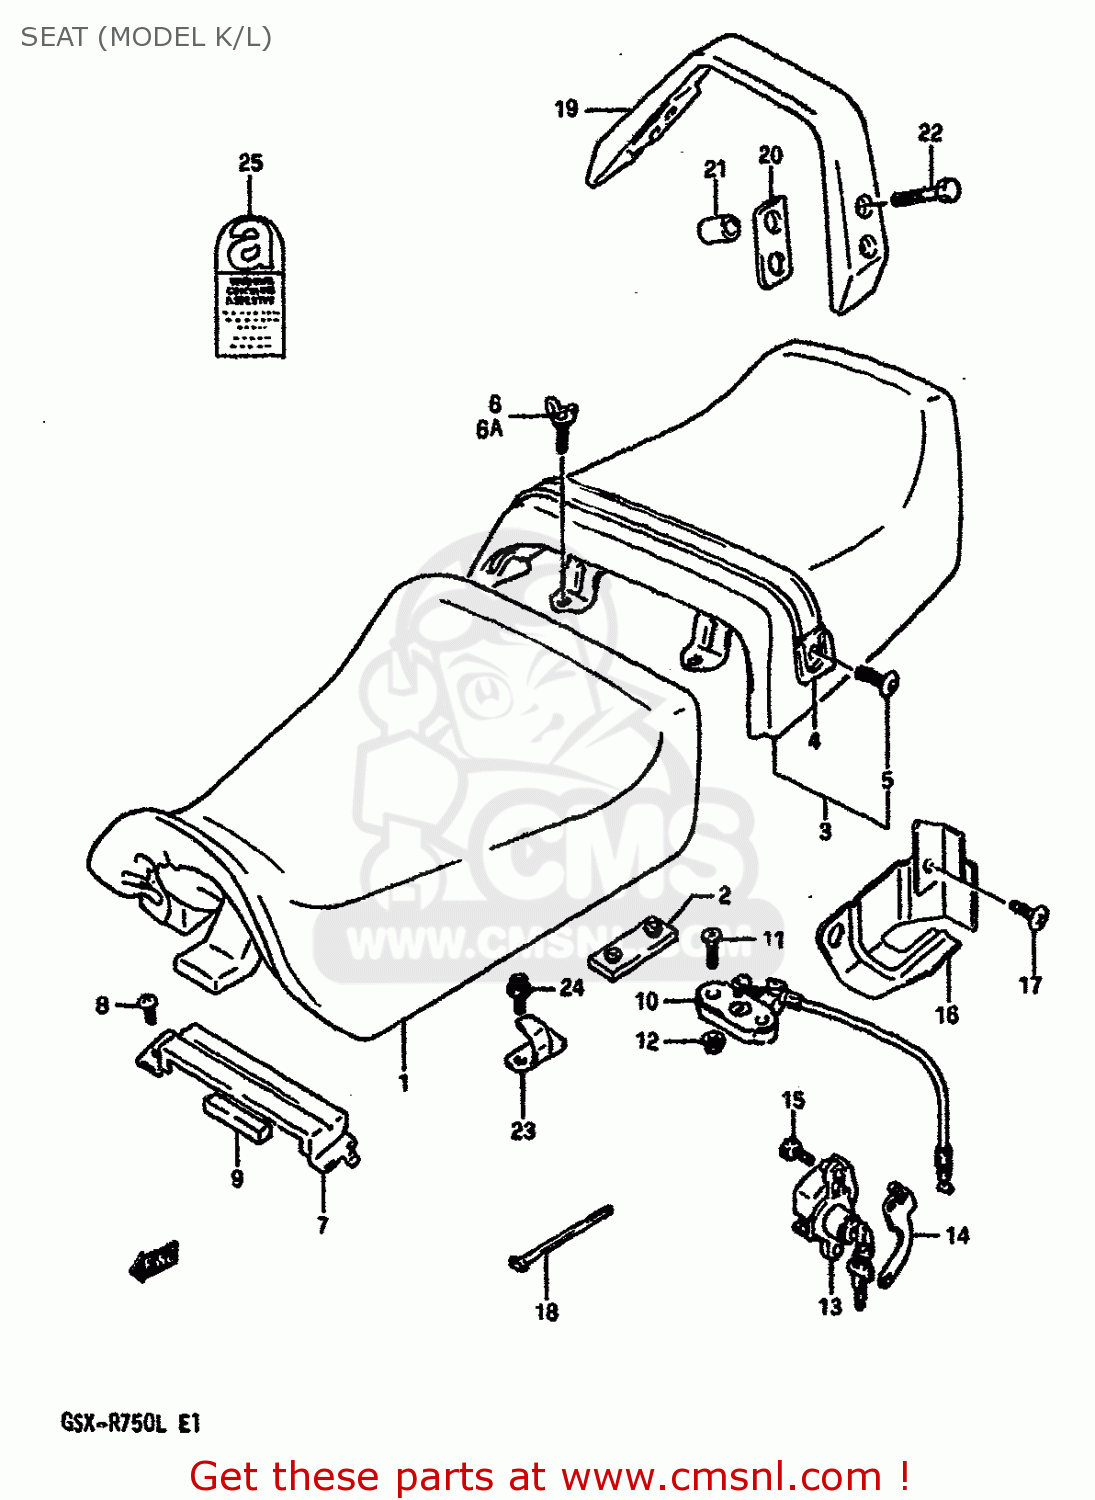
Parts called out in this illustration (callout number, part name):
1	SEAT ASSEMBLY
2	CUSHION
3	SEAT,PILLION
4	BAND,SEAT
5	BOLT
6	BOLT
6A	SCREW(6X20)
7	PLATE,SEAT SUPPORT RR
8	SCREW
9	CUSHION,PLATE SEAT SPRING
10	BRACKET,SEAT SUPPORT RR
11	SCREW
12	NUT
13	LOCK SET,SEAT
14	PLATE,SEAT LOCK
15	BOLT
16	PLATE,SEAT LOCK CABLE
17	BOLT
18	CLAMP
19	HANDLE,PILLION RIDER
20	CUSHION,PILLION RIDER HANDLE
21	SPACER(8.6X16X24)
22	BOLT
23	BOLT
25	LABEL,ASBESTOS WARNING
